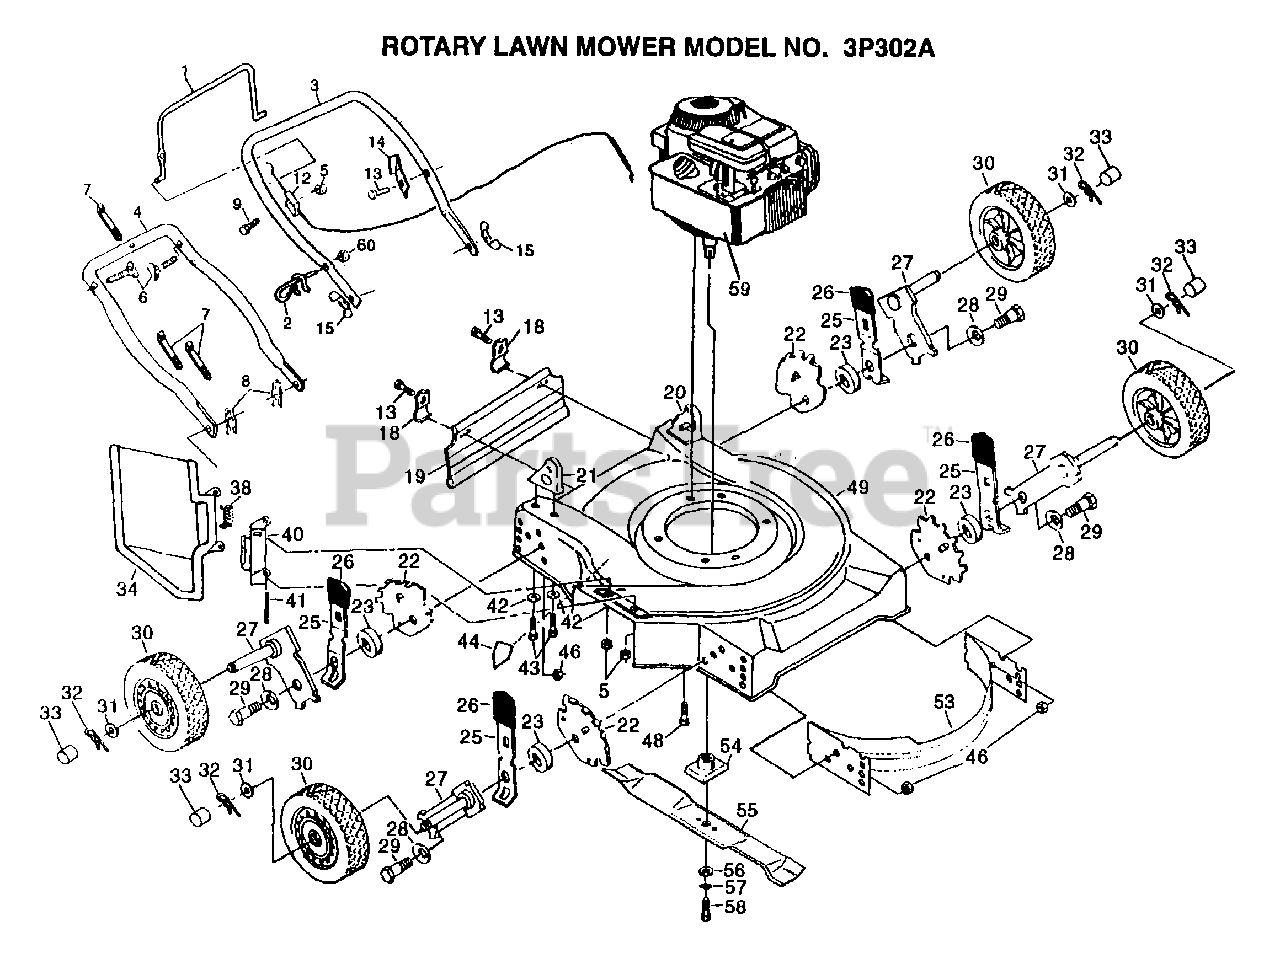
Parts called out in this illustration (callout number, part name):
1	CONTROL BAR
2	ROPE GUIDE
6	BOLT.HANDLE.LM
8	HAIRPIN COTTER
9	BOLT 1/4-20-1 1/2
12	"CABLE,ENG ZONE CO"
13	TAPPING SCREW
14	"BRKT,UPSTOP"
15	"NUT,WING PM"
18	"BRKT,DEFL PM"
19	SKIRT.REAR.22SD.
22	BRACKET.ADJ.9POS.
25	SPRING SELECTOR
26	KNOB PM
27	AXLE ARM
28	"WASHER, BELLEVIL."
29	BOLT SHLD 3/8-16
30	WHEEL.ASM
31	WASHER
32	RETAINER CLIP PM
34	GUARD.DISCH.22SD.
40	BRACKET.HINGE.W/F
41	ROD.HINGE.COMBI-C
42	STEEL WASHER
43	SCREW
44	DECAL HYT
46	LOCKNUT PM
48	SCREW
49	KIT.HSG.22SD.PUSH
53	BAFFLE.FRT/REAR
54	BLADE ADAPTOR
55	"BLADE.MULCH.22"""
56	"WASHER,HARDEN"
57	LOCKWASHER
58	SCREW
60	NUT
